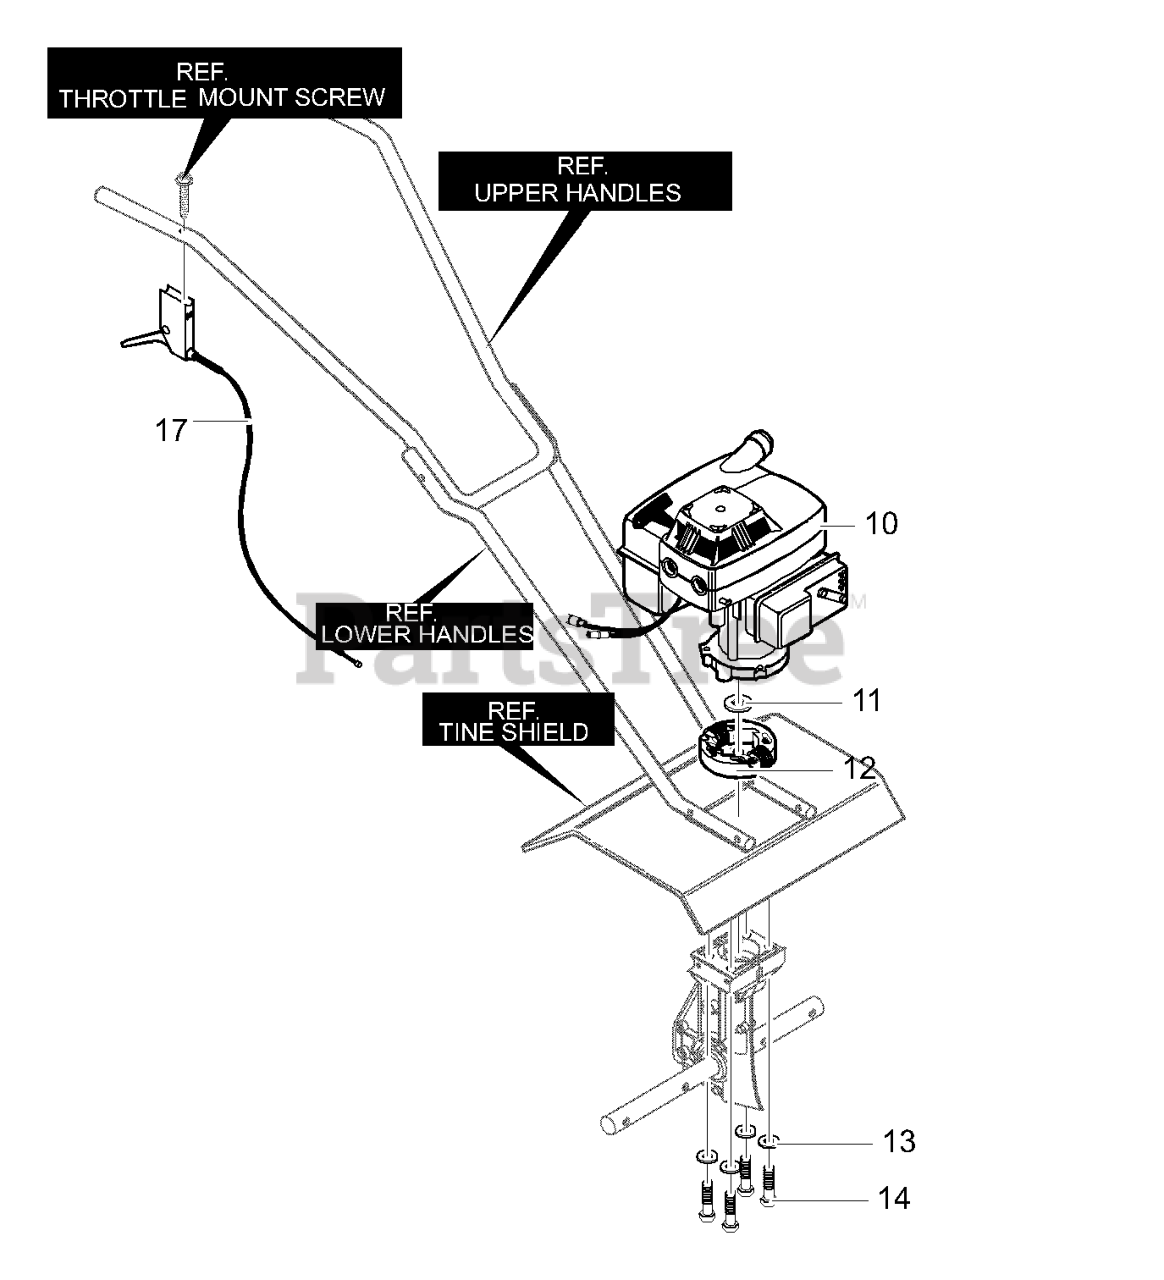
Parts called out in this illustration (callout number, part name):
10	Engine
11	Flat washer
13	Washer, Regsptlk
14	Bolt
17	Cable, Throttle
